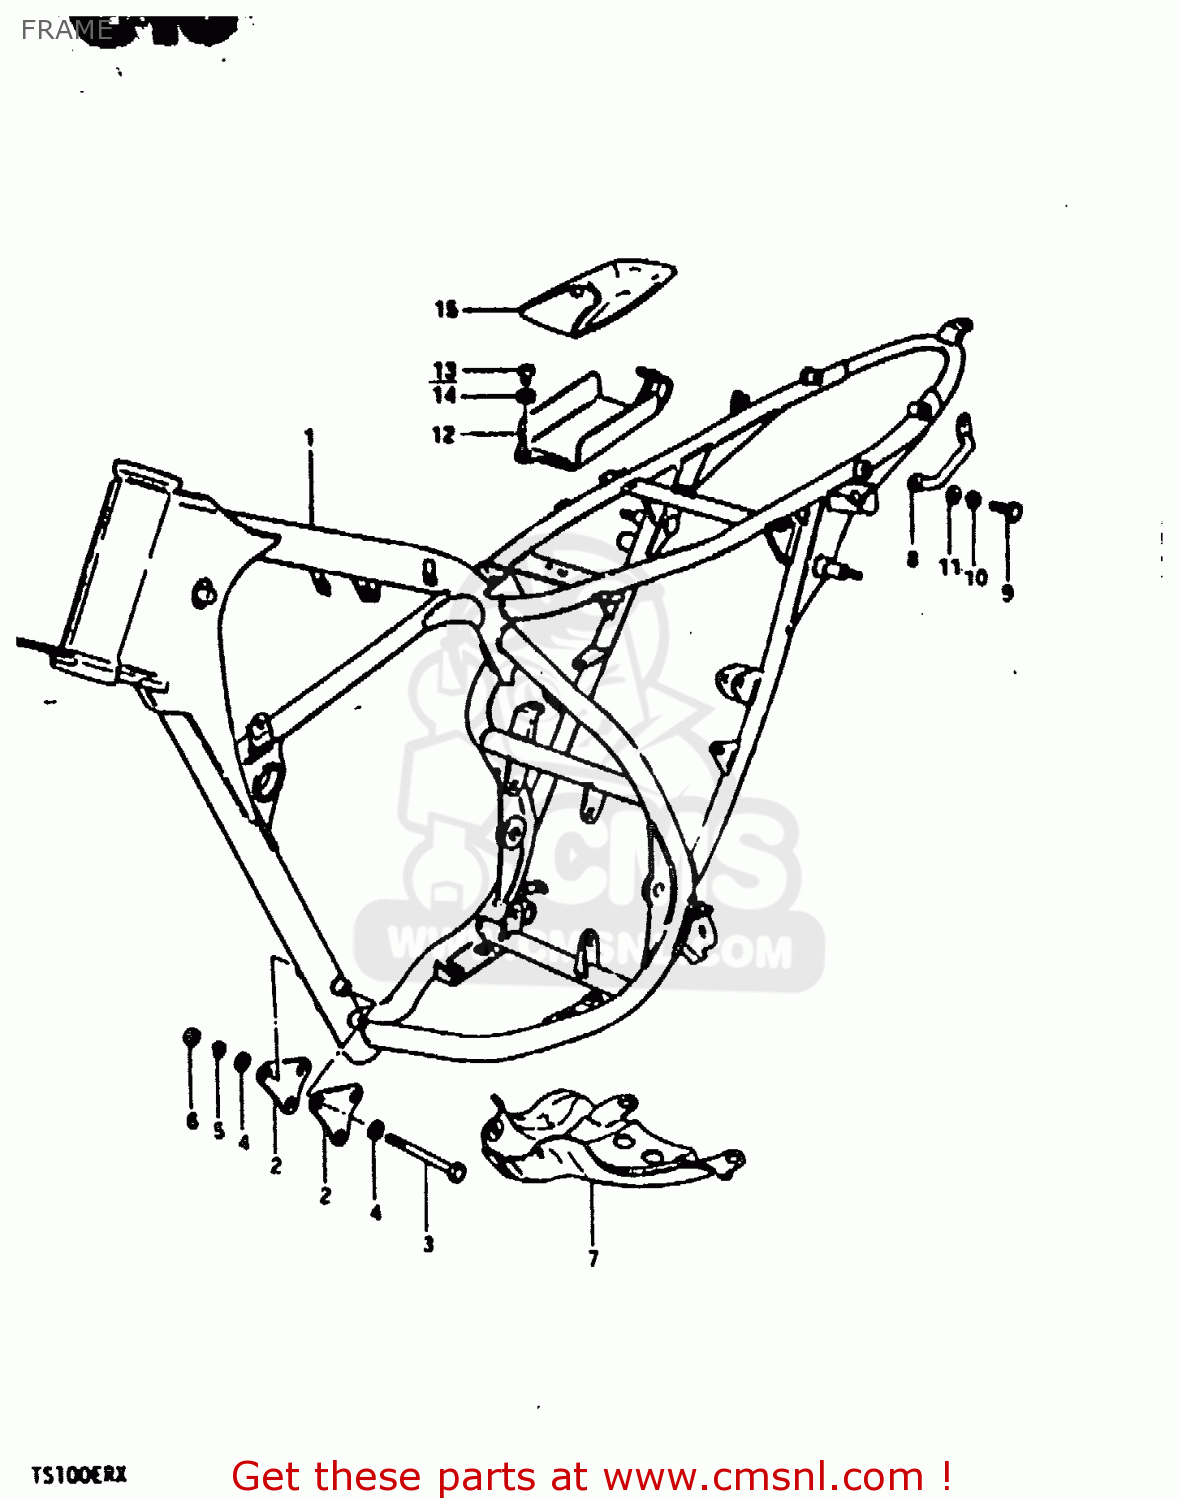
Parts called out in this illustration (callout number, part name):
1	FRAME
2	PLATE,ENG MTG
3	BOLT,8X75
4	WASHER
5	LOCK WASHER
6	NUT
8	GRIP,FRAME HANDLE
9	BOLT
10	LOCK WASHER
11	WASHER
12	HOLDER,TOOL
13	SCREW
14	WASHER
15	TOOL SET
